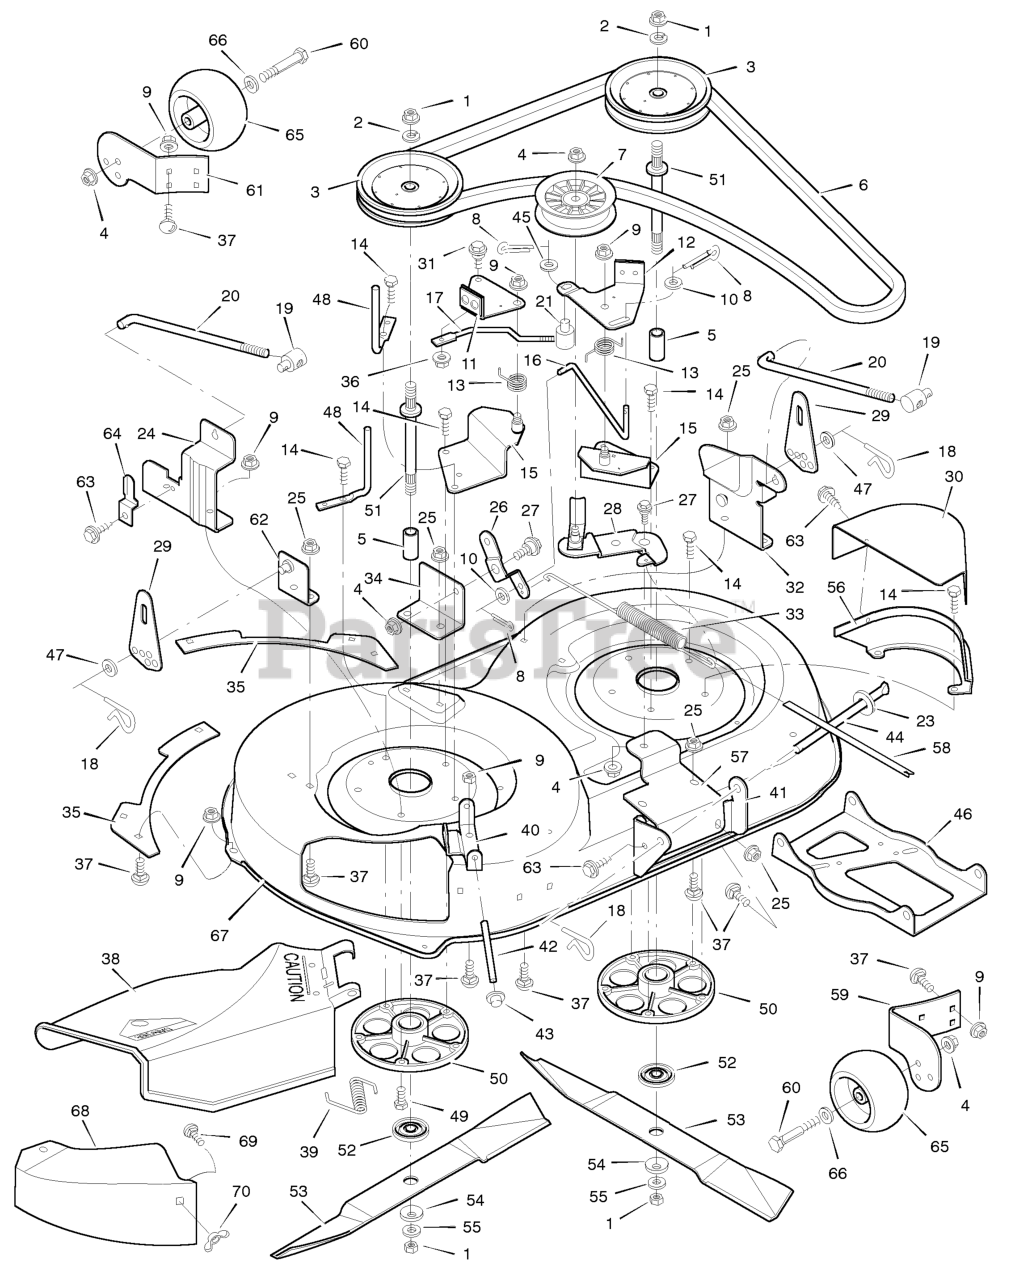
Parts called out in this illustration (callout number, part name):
1	Nut, Hex
2	Lockwasher
3	Pulley, Jackshaft
4	Locknut, Flange
6	Belt, Blade Drive
7	Pulley, Idler
8	Pin, Cotter
9	Locknut, Flange
11	Brake Assembly, Right
12	Brake Assembly, Left
13	Spring, Torsion
14	Bolt, Hex
15	Bracket Assembly, Brake
16	Rod, Brake
17	Rod, Cross Link
18	Pin, Hair
19	NUT, Adjusting, 1/2-13
20	Rod, Adjuster
21	Nut, Adjustable
24	Bracket, Right
25	Nut, Flange
26	Bracket, Pivot
27	Bolt, Carriage
28	Arm Assembly, Idler
29	Plate, Adjuster
30	Cover, Pulley
31	Bolt, Shoulder
32	Bracket Assembly, Left Lifter
33	Spring, Extension
34	Bracket, Pivot
36	Locknut, Flange
37	Bolt, Carriage
38	Deflector Assembly, Chute
39	Spring, Torsion
40	Bracket, Hinge
41	Bracket, Front Hanger
42	Rod, Deflector
43	Cap, Push On
44	Rod, Hanger
46	Hanger, Front
48	Rod, Belt Guide
49	Bolt, Hex
50	Housing, Jackshaft
51	Jackshaft
52	Adapter, Blade
53	Blade, 42" (Left)
54	Washer, Belleville
56	Bracket, Pulley Cover
57	Bracket, Idler Mount
58	Indicator, Plastic
59	Bracket, Right Wheel
60	BOLT, Gauge Wheel
61	Bracket, Left Wheel
62	Bracket Assembly, Right Lifter
64	Guide, Belt
65	Wheel, Gauge
66	Washer
67	Housing, Blade
68	Cover, Mulcher
69	Bolt, Carriage
70	Wingnut
